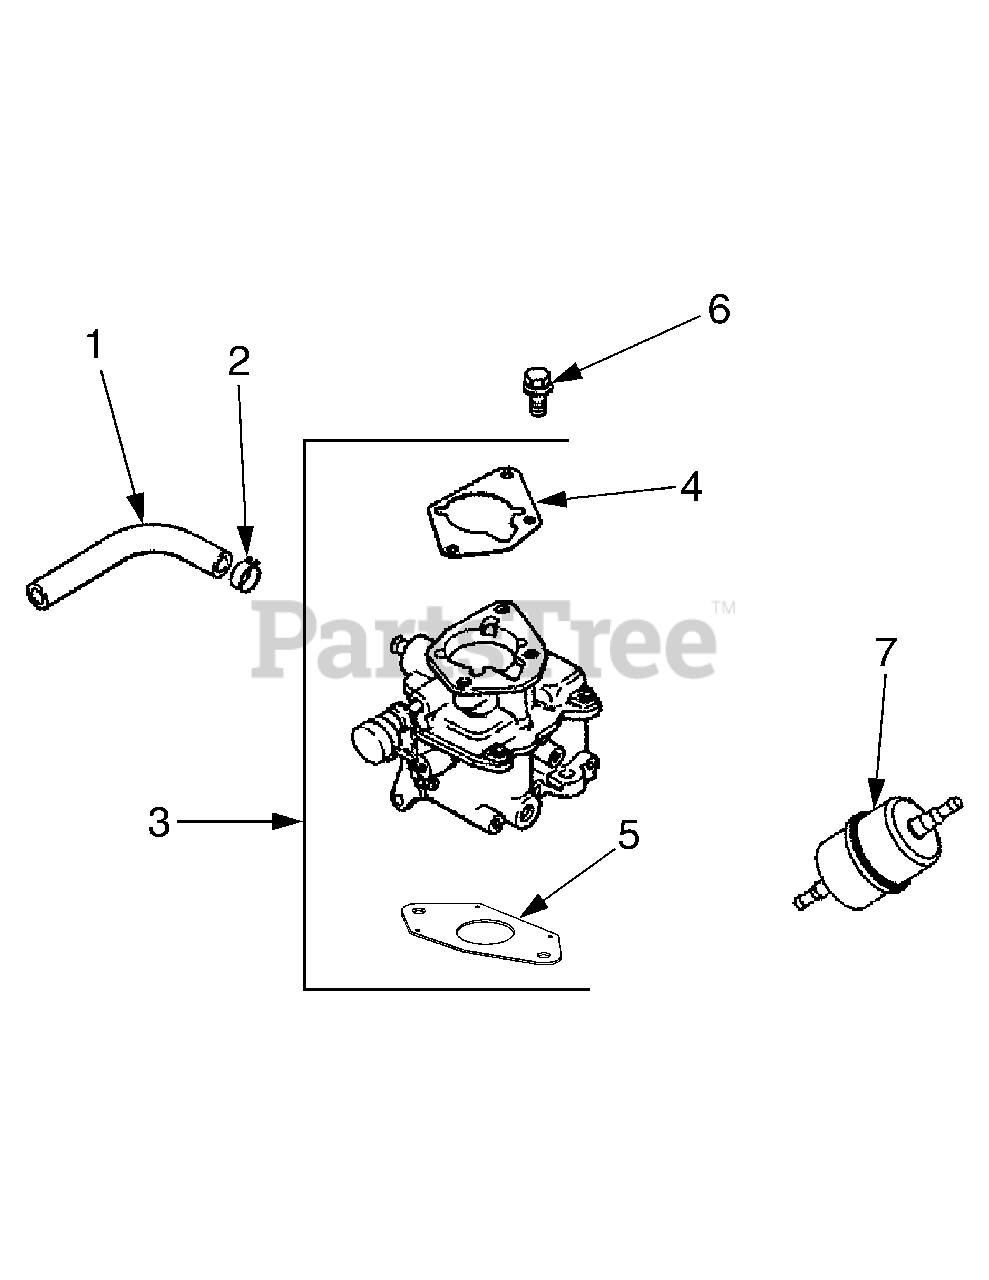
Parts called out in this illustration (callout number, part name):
1	Line, Fuel 24 length"
2	Clamp, Hose
3	Kit, Carburetor w/Gasket (Includes 4,6)
4	Gasket, Air Cleaner Base
5	Gasket, Carburetor
6	Screw, Hex Flange, M6 x 1.0 x 25
7	Filter, Fuel
